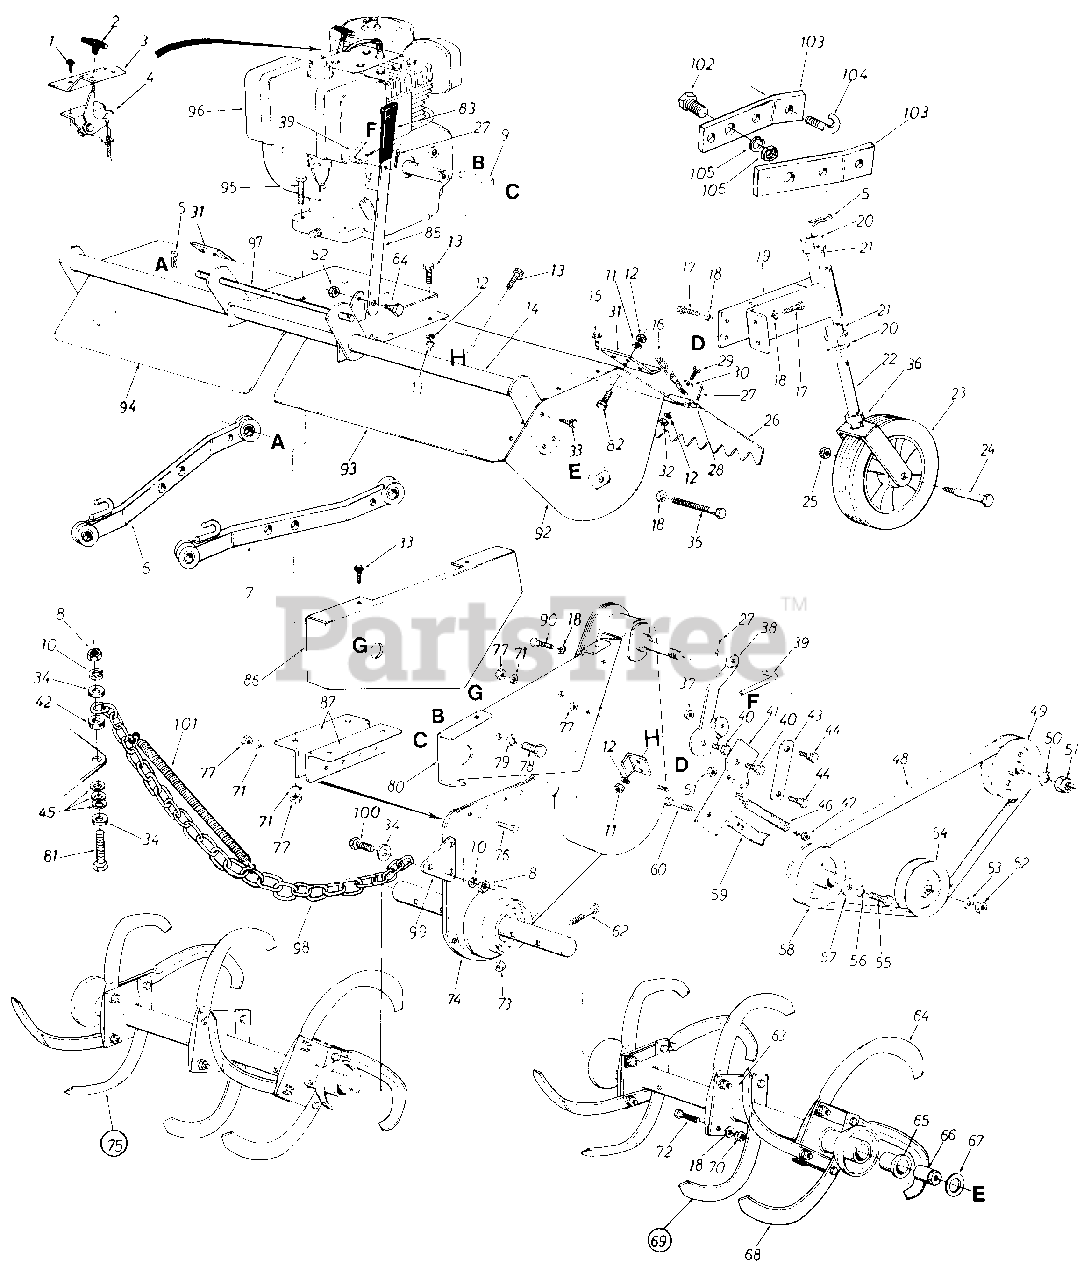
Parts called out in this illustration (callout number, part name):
1	Hex Wash. Hd. Self-Tap Scr. #8 x .50" Lg.
2	Throttle Control Knob
3	Throttle Control Bracket
4	Throttle Control Ass'y. Comp.
5	Internal Cotter Pin
6	Draft Bar Ass'y. R.H.
7	Draft Bar Ass'y. L.H.
8	Hex Nut 3/8-24 Thd.
9	Sq. Key 1/4" x 1/4" x 2.00" Lg.
10	L-Wash. 3/8" I.D.
11	Hex Nut 1/4-28 Thd.
12	L-Wash. 1/4" I.D.
13	Hex Bolt 1/4-28 x .62" Lg.
16	#2 Dog Chain x 20" Lg.
17	Hex Wash. Hd. Self-Tap Scr. 3/8-24 x .75" Lg.
18	L-Wash. 3/8 I.D.
21	Flange Bearing 3/4" I.D. x 1.00" O.D.
24	Shoulder Bolt .623" I.D. x 3.62" Lg.
25	Hex Cent. L-Nut 7/16-14 Thd.
28	L.H. Flap Rod
29	Hex Bolt 1/4-20 x .62" Lg.
30	Fl-Wash. 1/4" I.D.
33	Hex Wash. Hd. Self-Tap Scr. 1/4" x .62" Lg.
34	Fl-Wash. .385" I.D. x 1.0" O.D. x .135 Thk.
35	Hex Bolt 3/8-16 x 1.25" Lg.
36	Spacer.752" I.D. x 1.25" O.D.
37	Hex Cent. L-Nut 5/16-18 Thd.
40	Shoulder Bolt 7/16" Dia. x 1.75" Lg.
45	Fl-Wash. .406" I.D. x .74" O.D. x .063 Thk.
46	Extension Spring .62" O.D. x 6.12" Lg.
47	Hex Crown Nut 3/8-24 Thd.
48	"V"-Belt 1/2" x 43" Lg. (Kevlar)
49	1/2" "V"-Pulley 4.75" O.D. x .625" Bore
50	L-Wash. 5/8" I.D.
51	Hex Ins. L-Nut 5/8-18 Thd.
52	Hex Cent. L-Nut 3/8-16 Thd.
53	Fl-Wash. 3/8 I.D.
54	Idler Pulley 4.0" O.D.
55	Hex Bolt
56	L-Wash. 7/16" I.D.
57	Fl-Wash. 7/16" I.D. x 1.38" O.D.
58	1/2" "V"-Pulley .475" O.D. x 1.00" Bore
61	Hex Cent. L-Nut 5/16-18 Thd.
62	Hex Bolt 7/16-14 x 2.00" Lg.
66	Spacer
67	Thrust Wash. 1/2" I.D. x 1.55" O.D.
71	L-Wash. 5/16" I.D.
72	Hex Bolt 3/8-24 x 1.5" Lg.
73	Hex Cent. L-Nut 7/16-14 Thd.
77	Hex Nut 5/16-18 Thd.
78	Hex Bolt 1/2-20 x .88" Lg. Grade 5
79	L-Wash. 1/2" I.D.
80	Clutch Support Bracket
81	Hex Bolt 3/8-24 x 1.75" Lg.
82	Hex Bolt 1/4-28 x .75" Lg.
83	Plastic Grip
84	Shoulder Bolt .498 Dia. x .212 Lg.
85	Clutch Handle
96	8 H.P. Engine
97	Tiller Mounting Shaft 16" Lg.
98	Chain 2.3" Lg.
99	Tiller Mounting Bracket
100	Hex Bolt 3/8-24 x 1.25" Lg.
101	Extension Spring
102	Hex Bolt 5/8-18 x 1.62"
103	Drag Link Extension
104	Hitch Chain Hook
105	L-Wash. 5/8" I.D.
106	Hex Jam Nut 5/8-18 Thd.
